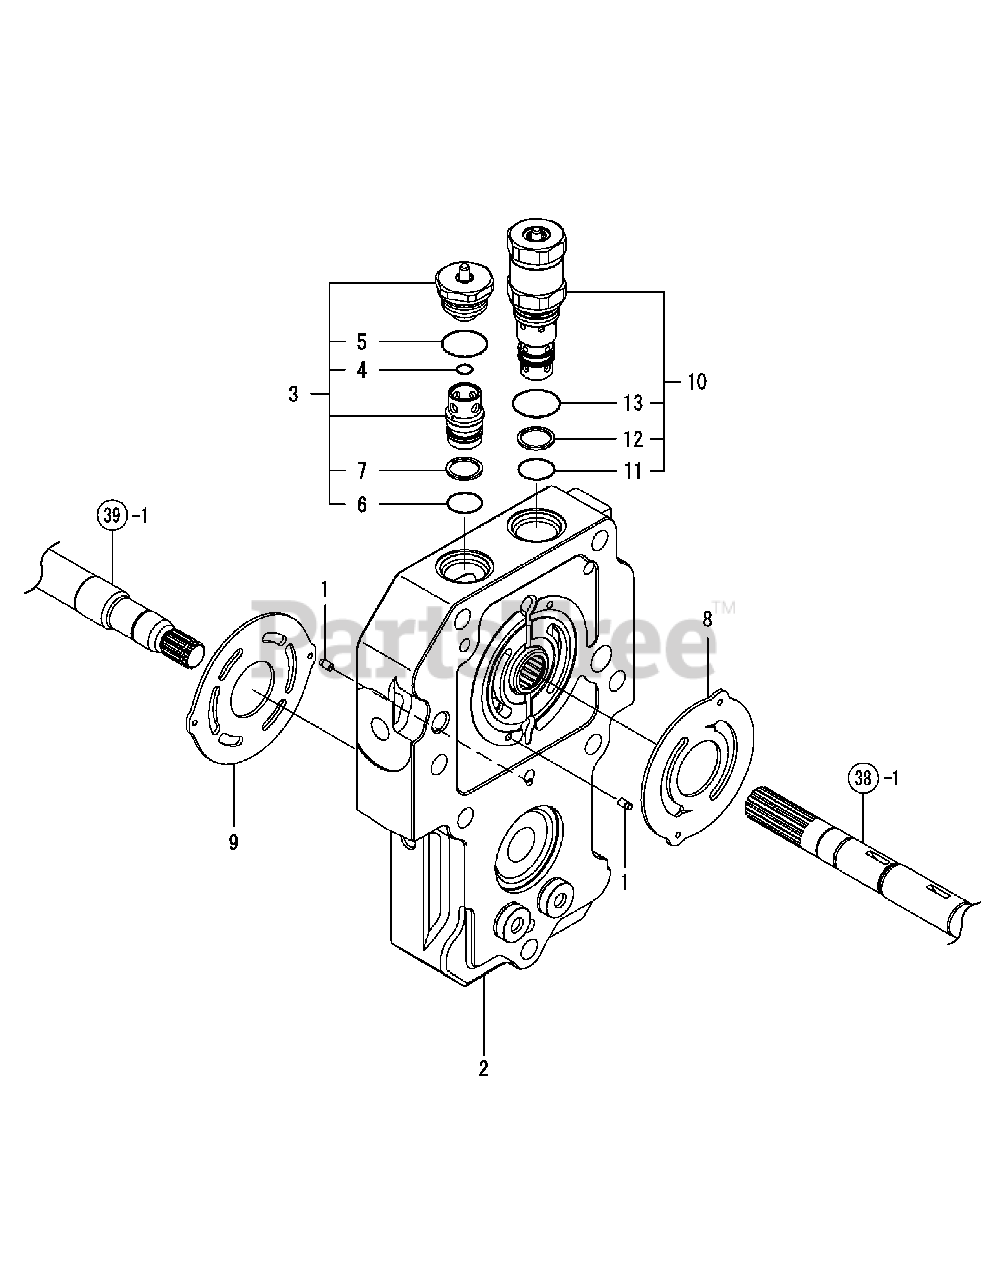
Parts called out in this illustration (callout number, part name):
1	PIN, KNOCK 3.5
2	CENTER CASE K93 CMP
3	CHECK VALVE (R CMP
4	O-RING 1A P-5.0
5	O-RING 1A P-20.0
7	RING, BACK UP 18
10	RELIEF ASSY,TOW 25
12	RING, BACK UP 18
13	O-RING 1A P-20.0
